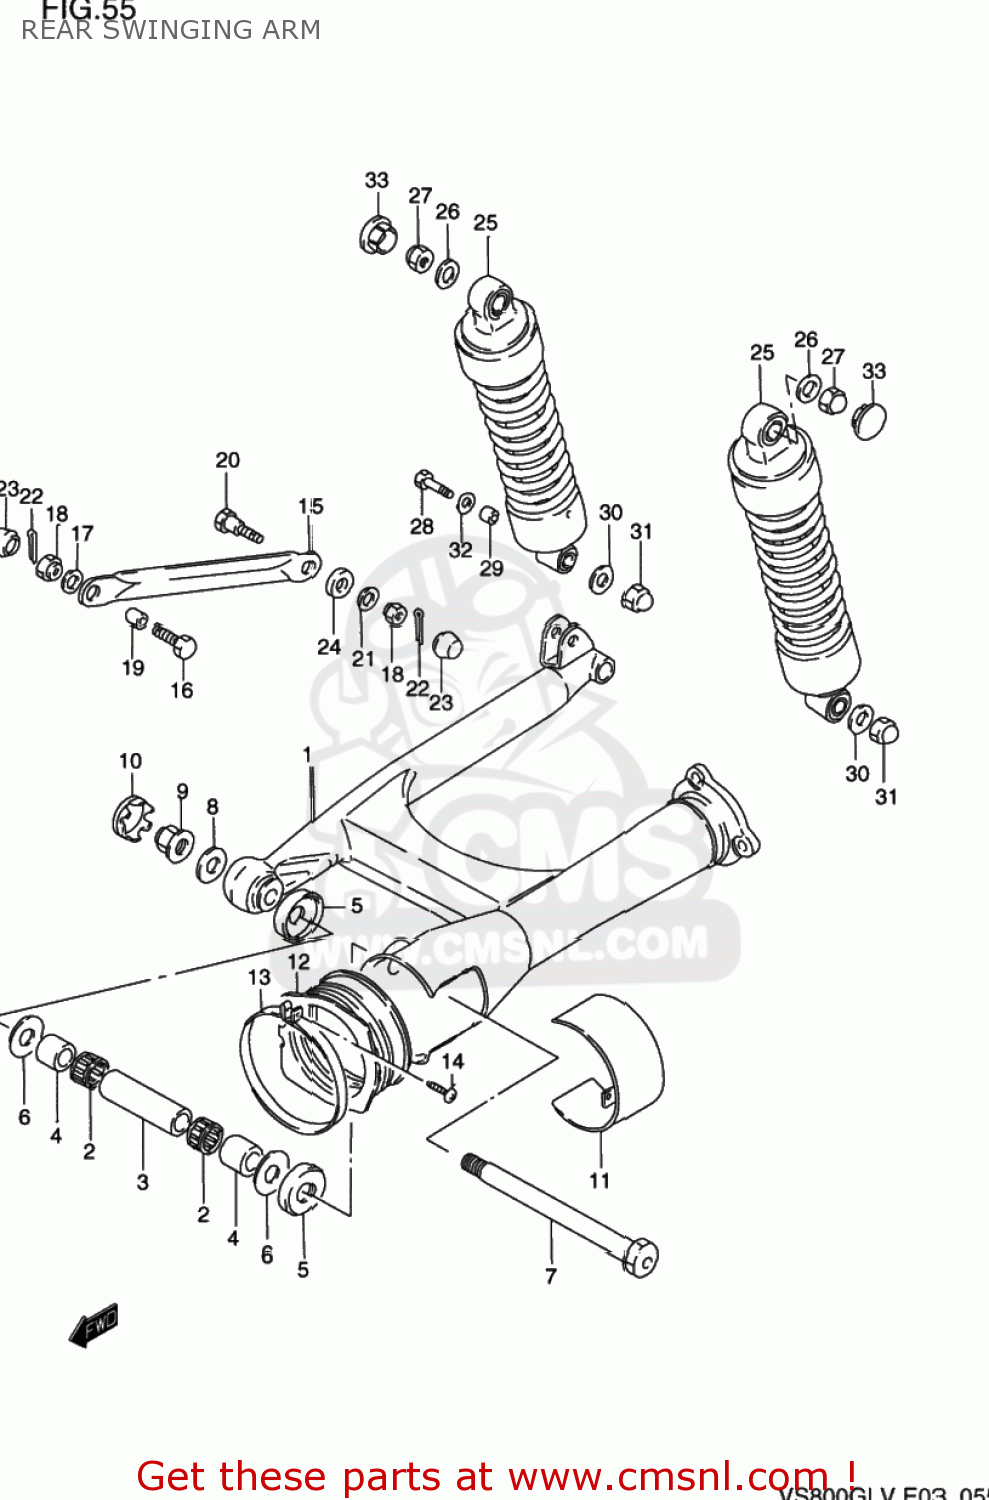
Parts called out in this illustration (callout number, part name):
1	SWINGINGARM,RR
2	BEARING(22X29X20)
3	SPACER,RR SWGARM PIVOT
4	SPACER,RR SWGARM PIVOT
5	SEAL,RR SWGARM PIVOT DUST
6	WASHER
7	SAHFT,RR SWGARM PIVOT
8	WASHER(17X30X3)
9	NUT 16MM
10	CAP,RR SWINGING ARM PIVOT,R
11	COVER,REAR SWING ARM PIVOT
12	BOOT,PROPELLER SHAFT
13	CLAMP
14	SCREW
15	TORQUELINK,RR
16	BOLT(10X28)
17	WASHER
18	NUT
19	SPACER
20	BOLT(10X41)
21	WASHER (10X20X2.3)
22	PIN 16X20
23	CAP
24	CUSHION
25	ABSORBER ASSEMBLY,REAR SHOCK
26	WASHER
27	NUT
28	BOLT(10X39)
29	SPACER (10.2X14X20.7)
30	WASHER
31	NUT
32	WASHER 10MM
33	CAP,FRAME HANDLE GRIP
